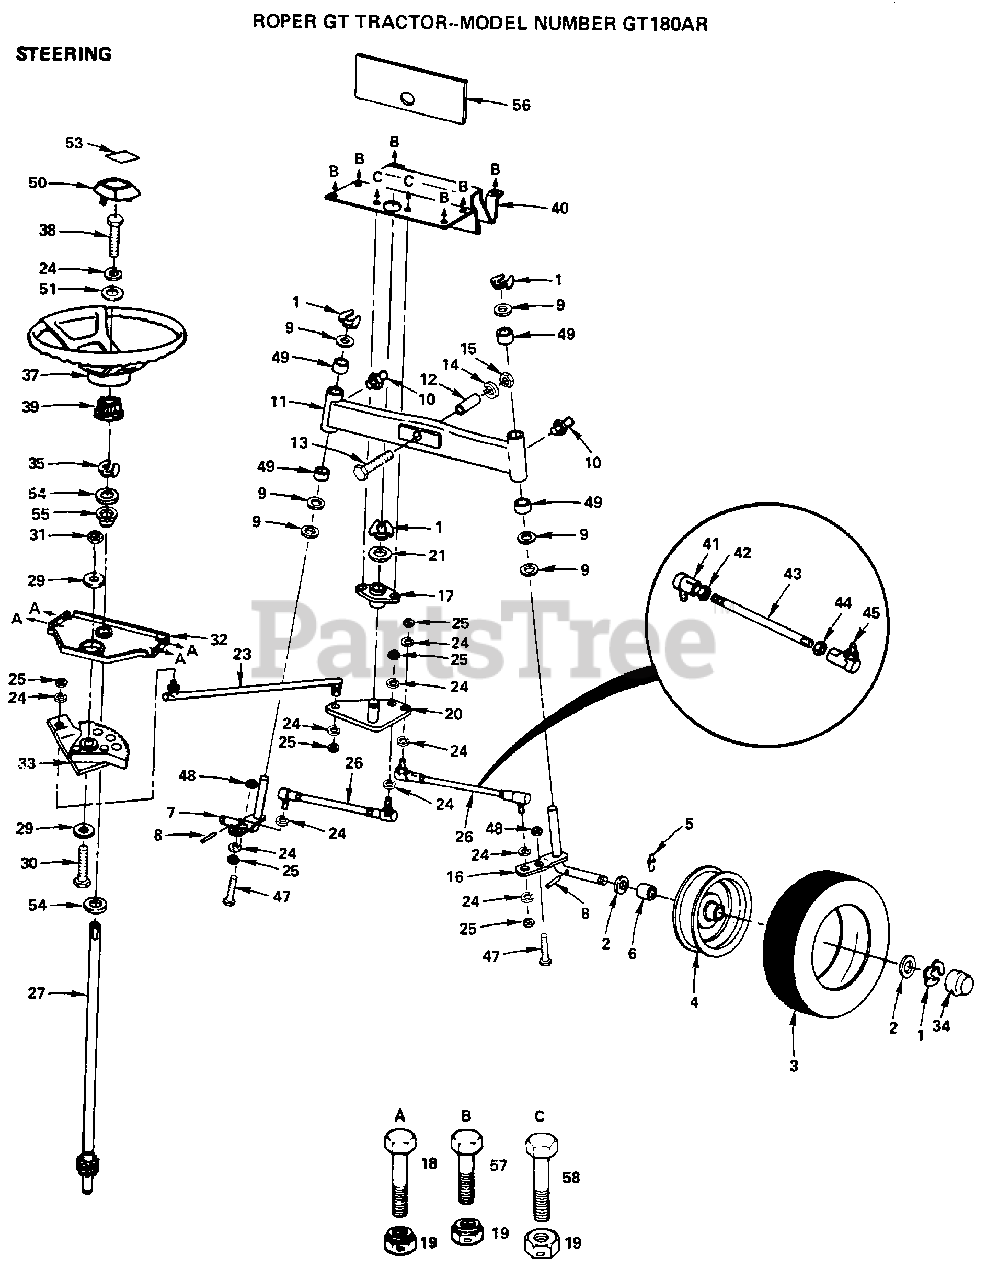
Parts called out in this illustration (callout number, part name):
1	RING
5	ZERK FITTING M
6	"FLANGE, BEARING"
9	WASHER .T
10	ZERK M
13	BOLT
14	WASHER
15	NUT X
18	BOLT
21	WASHER
24	LOCKWASHER
27	SHAFT STEERING GT
29	WASHER GT
30	BOLT
31	NUT LTV
33	SECTOR ASSY GT
34	HUB CAP
35	KLIP RING
39	ADAPTER LT
42	NUT
44	NUT
47	BOLT, HEX 3/8 - 16 X 2
48	NUT
49	BRNG. T
50	INSERT-WHEEL LT
53	DECAL - STEERING WHEEL
54	WASHER .T
55	"FLANGE GT, BEAR."
58	BOLT
